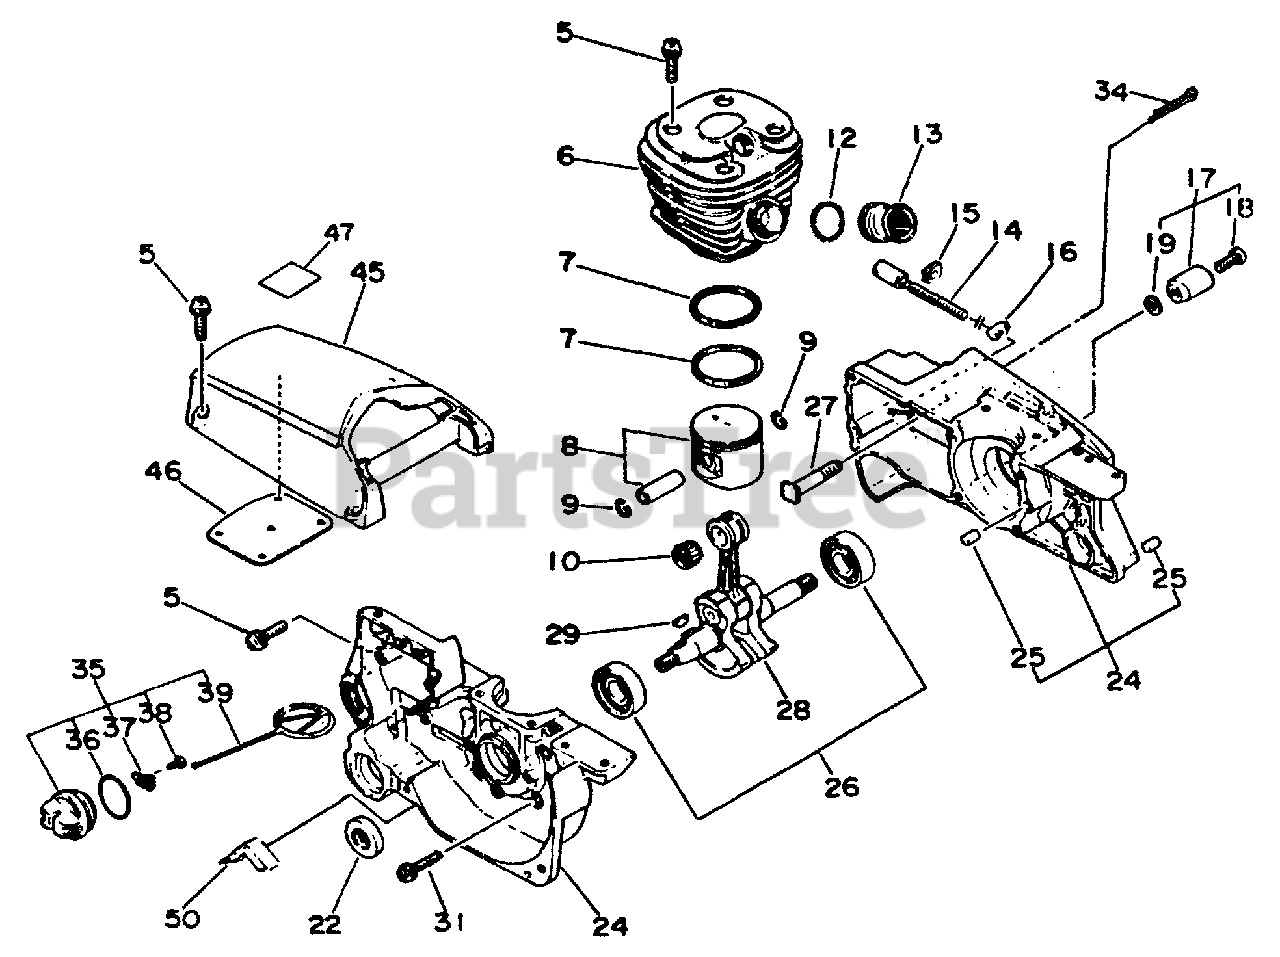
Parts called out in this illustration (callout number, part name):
5	SCREW - 5×20
6	CYLINDER
7	RING, PISTON
8	PISTON KIT
9	RING, SNAP 8
10	BEARING, NEEDLE
12	BAND
13	BELLOWS, INTAKE
14	SCREW, ADJUSTER
16	TENSIONER
17	CHAIN CATCHER KIT
18	SCREW - 5×20
19	WASHER, FLAT 5.5×10×0.8
22	SEAL, OIL
24	CRANKCASE KIT
25	PIN, LOCATING 5×10
26	BEARING SET
27	STUD, GUIDE BAR 8
28	CRANKSHAFT ASSY
29	KEY, WOODRUFF
31	SCREW - 5×30
34	PIN, COTTER
35	CAP ASSY
37	RETAINER, CONNECTOR
38	SCREW 3×8
39	CONNECTOR, CAP L= 60 MM
45	COVER, CYLINDER
47	LABEL - KICK BACK
50	CUSHION
